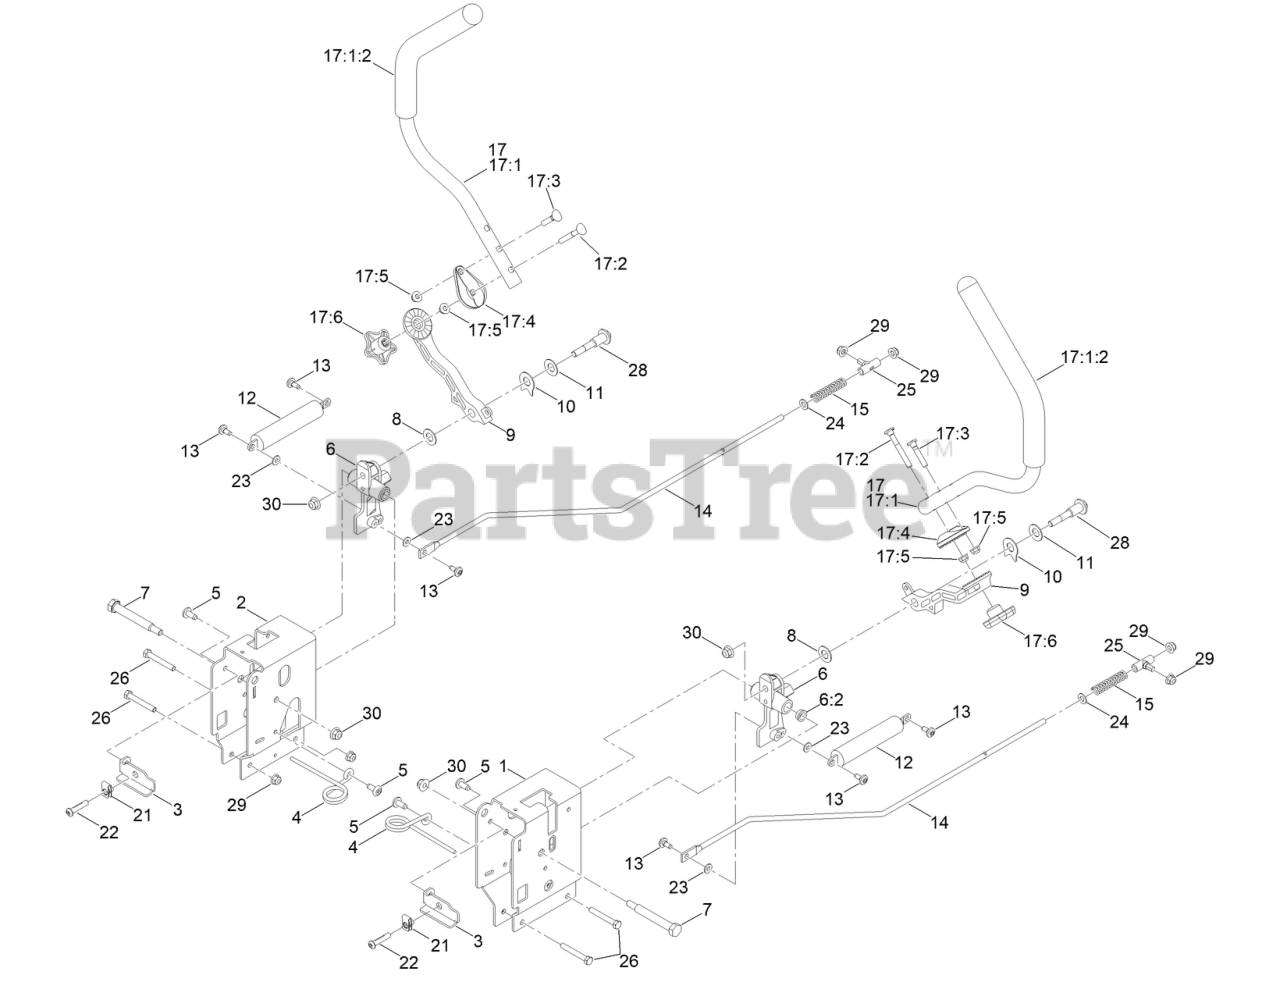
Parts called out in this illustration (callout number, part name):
1	CONTROL BOX - LH G7
2	CONTROL BOX - RH G7
3	ADJUSTMENT PLATE-CONTROL BOX
4	SPRING-TORSION
6	PIVOT ARM ASM
6:2	BUSHING-FLANGE
7	BOLT-PIVOT
8	WASHER-NYLON
9	ARM-CONTROL, 32 TEETH
10	SPACER, ANTI-ROTATION
11	WASHER-BELLEVILLE
12	DAMPER-NON CAVITATING
13	SCREW-SHOULDER
14	ROD - HYDRO, LH
15	SPRING-COMPRESSION
17	CONTROL HANDLE ASM
17:1	HANDLE-CONTROL
17:2	SCREW-HANDLE
17:3	SCREW-HANDLE
17:4	DISC-ADJUSTMENT HANDLE, 32 TEETH
17:5	NUT-HF
17:6	KNOB-HANDLE
22	SCREW-HSBH
23	WASHER
24	WASHER-PLAIN
25	MOUNT-ROD, HYDRO
26	SCREW-HH
28	BOLT-PIVOT
29	NUT-HF, NI
30	NUT-HF, NI
